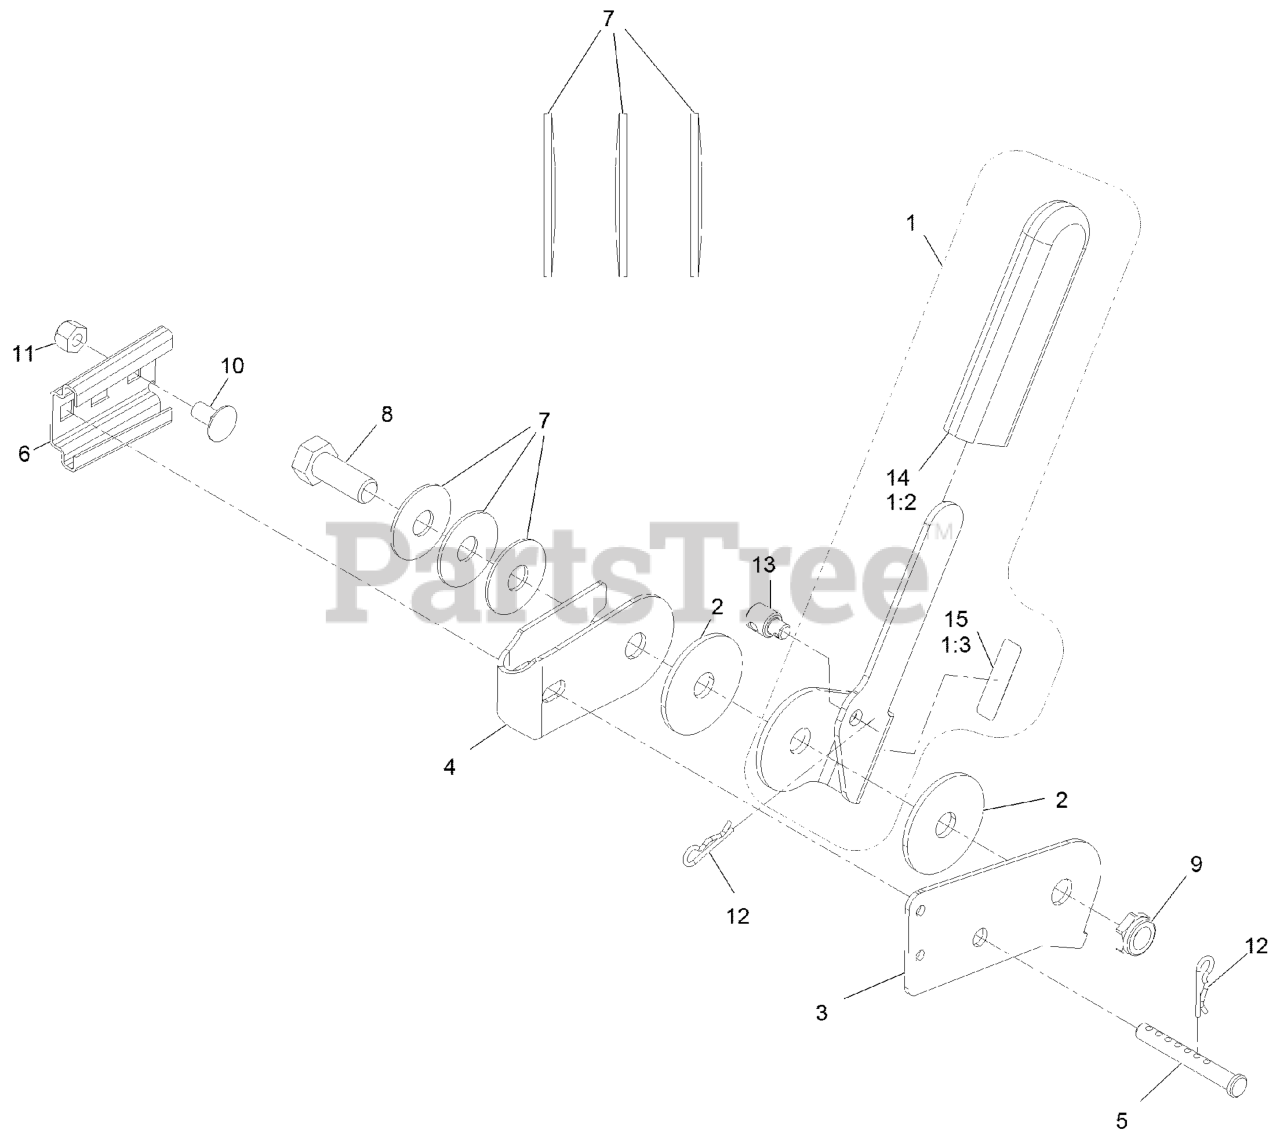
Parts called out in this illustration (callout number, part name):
1	CONTROL HANDLE ASM-OCD
1:2	GRIP-LEVER
1:3	DECAL-OPERATION
2	DISC-FRICTION
3	BRACKET,CONTROL MOUNT
4	BRACKET,HANDLE MOUNT
5	PIN-CLEVIS
6	BRACKET-MOUNTING,SMV
7	WASHER-DISC, SPRING
8	SCREW-HH
9	NUT-HEX
10	SCREW-CARR
11	NUT-LOCK, NI
12	PIN-COTTER
13	PIVOT, CONTROL CABLE
14	GRIP-LEVER
15	DECAL-OPERATION
